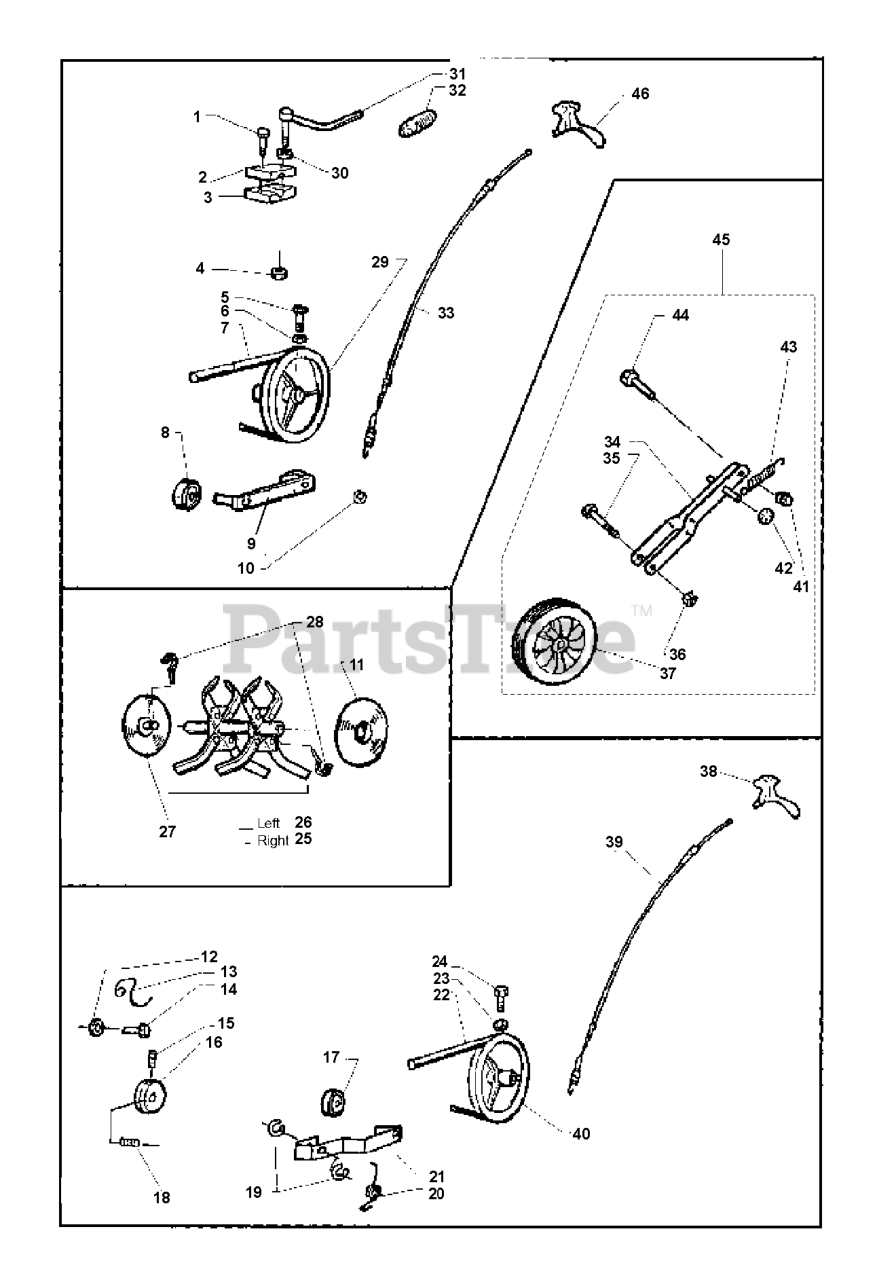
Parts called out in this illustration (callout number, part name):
1	Battery 12 Volt 25 Amp
2	BOLT.HEX.1/4.X.3/4.DICHROMATE
8	BOX.BATTERY.MNT.REAR.L
16	SWITCH INTERLOOK PUSH-IN
21	HARNESS ASSY LIGHT
25	CABLE.STARTER.6G.BL/RED.17.5
26	FUSE 20AMP
27	NUT
28	CABLE.BLACK.18"REAR.BA
29	SWITCH.SEAT.DELTA.OPC.
30	SWITCH.IGN.DELTA.W.LGH.ROS
33	KEY.CHAIN.BLISTER.PACK.GEN.INT
40	HARNESS.IGN.ELE.RELAY.TEX.46"
41	SCREW
42	TERMINAL COVER
43	SOLENOID.W/BRASS.PLUNGER
46	RP.GUAGE.SRVCMNDR.HRMTR.
50	RP.PTO.SWITCH.8 TERMINAL.BLACK
55	SCREW 5/16"
59	OUTLET.12-VOLT
71	HARNESS.IGN.CHASS.TEX.REAR.BAT
79	BULB HOLDER ASM.
81	RELAY HARNESS.SEALED
90	COVER.TERMINAL.BATTERY
101	PIGTAIL.MATNLK.NEW.HAR
102	HARNESS PIGTAIL PCH TEX ROS
103	HARNESS PIGTAIL 12V OUTLET
105	REVERSE SWITCH
